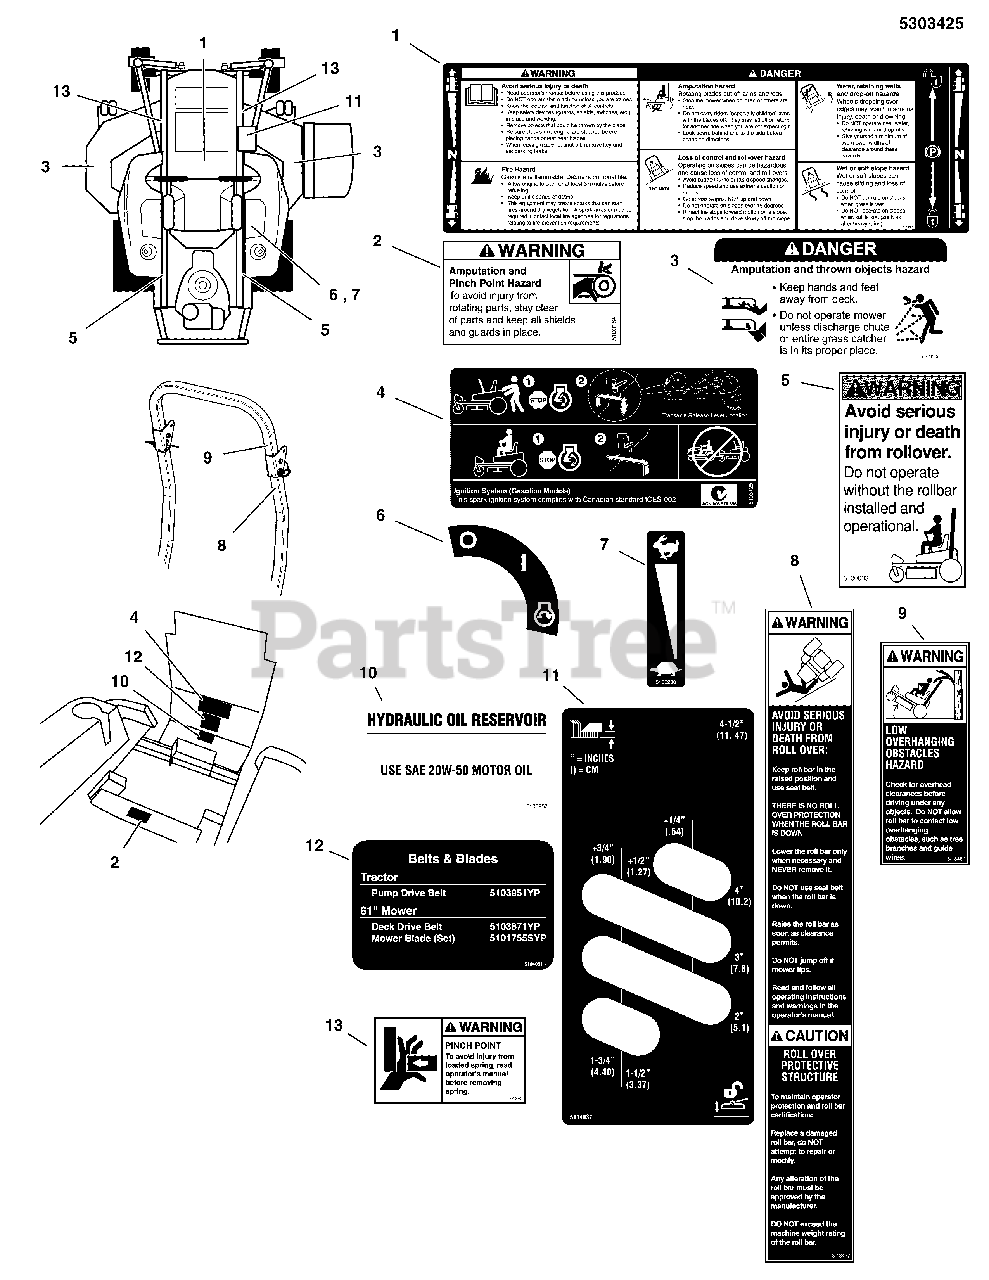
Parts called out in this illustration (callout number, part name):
1	DECAL, MAIN SAFETY
2	DECAL, WARNING, HAND IN BELT, ENG ONLY
3	DECAL, DANGER DO NOT OPERATE W/O DEFLECT
4	DECAL, TRANSAXLE RELEASE, 600/700
5	DECAL, WARNING, ROLL BAR
6	DECAL, IGNITION SWITCH
7	DECAL, THROTTLE CONTROL
8	DECAL, WARNING & CAUTION, ROPS (SV)
9	DECAL, WARNING OVERHANG, ROPS (SV)
10	DECAL, HYDRAULIC OIL, SAE 20W50
11	DECAL, CUT HEIGHT, SNAPPER 550
12	DECAL, BELT & BLADE, 550Z/2950, 52" & 61"
13	DECAL, PINCH POINT
